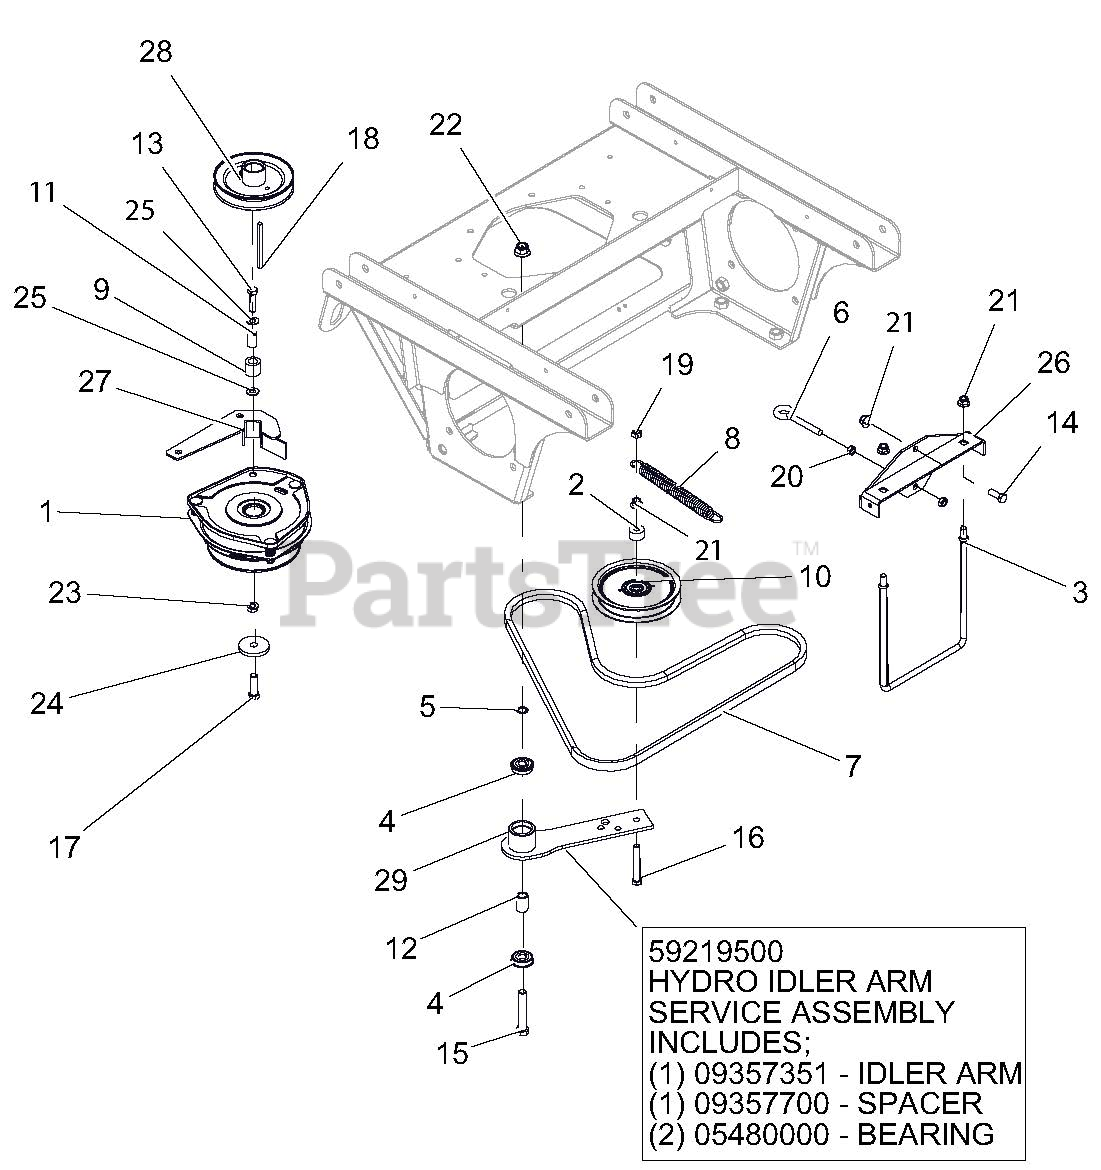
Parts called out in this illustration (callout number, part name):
1	CLUTCH-OGURA
2	SPACER .390X1.000X.562
3	ROD, BRAKE MTG
4	BRG, BALL .501 X 1.38 X .438 SEALED
5	WASHER-FLAT-STL, .500 X .750 X .020
6	BOLT, EYE .375-16
7	BELT, B RAW COGGED
8	SPRG, EXTENSION .120X.845X6.55 WLD
9	BUMPER, RUBBER .62 X 1.0 X .88 LG
10	IDLER, FLAT - 5.00" X .75"
11	BUSH.,S.391X.622X.95 ST REV A
12	SPACER, .510 X .750 X 1.148
13	BLT-HEX .38-16X1.50 GR5 YWZC
14	BLT-HEX .38-16X1.00 GR5 YWZC
15	BLT-HEX .50-13X3.00 GR5 YWZC
16	BLT-HEX .38-16X2.75 GR5 YWZC
17	BLT-HEX .44-20X1.50 GR8 YWZC
18	KEY-SQ .250X.250X3.50
19	NUT-LK-CTR .38-16 YWZC
20	NUT, JAM .375-16 YWZC
21	NUT-LK-NYL-FLG .38-16 YWZC
22	NUT-LK-NYL-FLG .50-13 YWZC
23	NUT, LK-TOP-FLG .38-16 YWZC
24	WSHR-FL-STL .469X2.00X.25 YWZC
25	WSHR-FL-STL.406X.812X.065 YWZ
26	WMT, SPRING ANCHOR BRKT
27	WMT, CLUTCH STOP - BLACK
28	SHEAVE, ENGINE 1.127 ID X 5.250 OD
29	WLDMT, HYDRO DRIVE IDLER ARM
29	HYDRO IDLER ARM SERVICE ASSEMBLY
29	IDLER ARM
29	SPACER
29	BEARING
